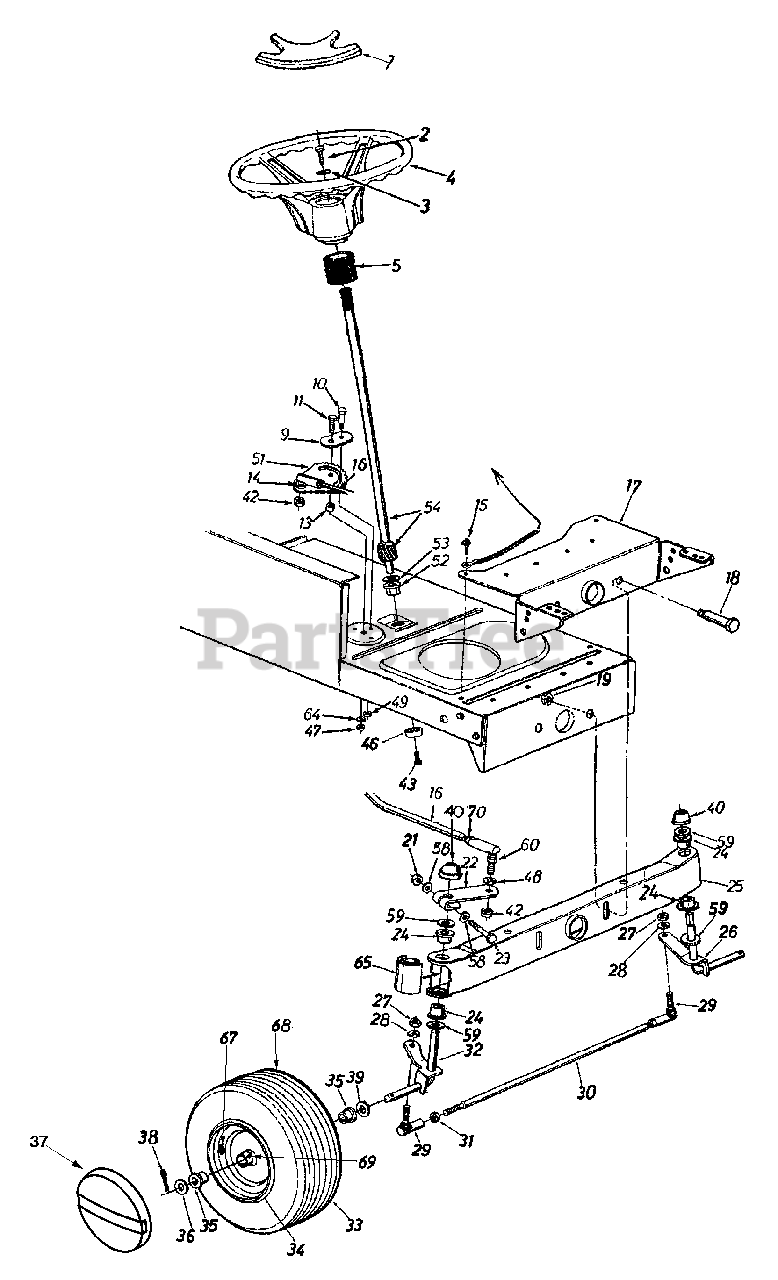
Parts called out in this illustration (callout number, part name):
1	Steering Wheel Cap
2	Hex Bolt 5/16-18 x 1" Lg.
3	Belleville Wash. .345" I.D.
4	Steering Wheel
5	Steering Bellow - 9"
9	Retainer Plate
10	Shoulder Bolt .437" Dia. x .35 Lg. 5/16-18
11	Hex Bolt 3/8-24 x 1.0" Lg. (Gr. 5)
13	Spacer .380" I.D. x .625" O.D. x .227
14	L-Wash. 3/8" I.D. (H.D.)
15	Hex Wash. Hd. Self-Tap Scr.
16	Steering Drag Link
18	Shoulder Bolt .498" Dia. x 2.04 Lg. 3/8-16
19	Flanged L-Nut 3/8-16 Thd.
21	Hex L-Nut 5/16-24 Thd.
22	Steering Arm Front Axle
23	Hex Bolt 5/16-24 x 2.00" Lg. (Gr.5)
24	Hex Flg. Brg. .632 I.D.
26	Front Axle Ass'y. - L.H.
27	Hex Nut 3/8-24 Thd.
28	L-Wash. 3/8" I.D.
29	Ball Joint 3/8-24 Thd.
30	Tie Rod (Adjustable)
31	Hex Jam Nut 3/8-24 Thd.
32	Front Axle Ass'y. - R.H.
36	Fl-Wash. .635 I.D. x 1.59" O.D.
37	Front Wheel Hub Cap
38	Cotter Pin 1/8" Dia. x 1.25"
39	Fl-Wash. 5/8" x 1.004 x .120
40	Push Cap 5/8" Dia. Rod
42	Hex Jam Nut 3/8-24 Thd.
43	Hex Patch Bolt 5/16-18 x .62
46	Cap
47	Hex Cent. L-Nut 3/8-24 Thd.
48	L-Wash. 3/8" I.D.
49	Hex Cent. L-Nut 5/16-18 Thd.
51	Steering Gear Segment
52	Hex Flg. Brg. .634 I.D.
53	Fl-Wash. (Hardened)
54	Steering Shaft
58	Wave-Wash. .32" I.D. x .62" O.D.
59	Fl-Wash. (Hardened)
60	Drag Link Ball Joint 7/16-20 Thd.
64	Bell-Wash. .39" I.D. x 1.38" O.D.
65	Pivot Bar End Cap
67	Valve - Air
69	Grease Fitting
70	Jam Nut 7/16-20
